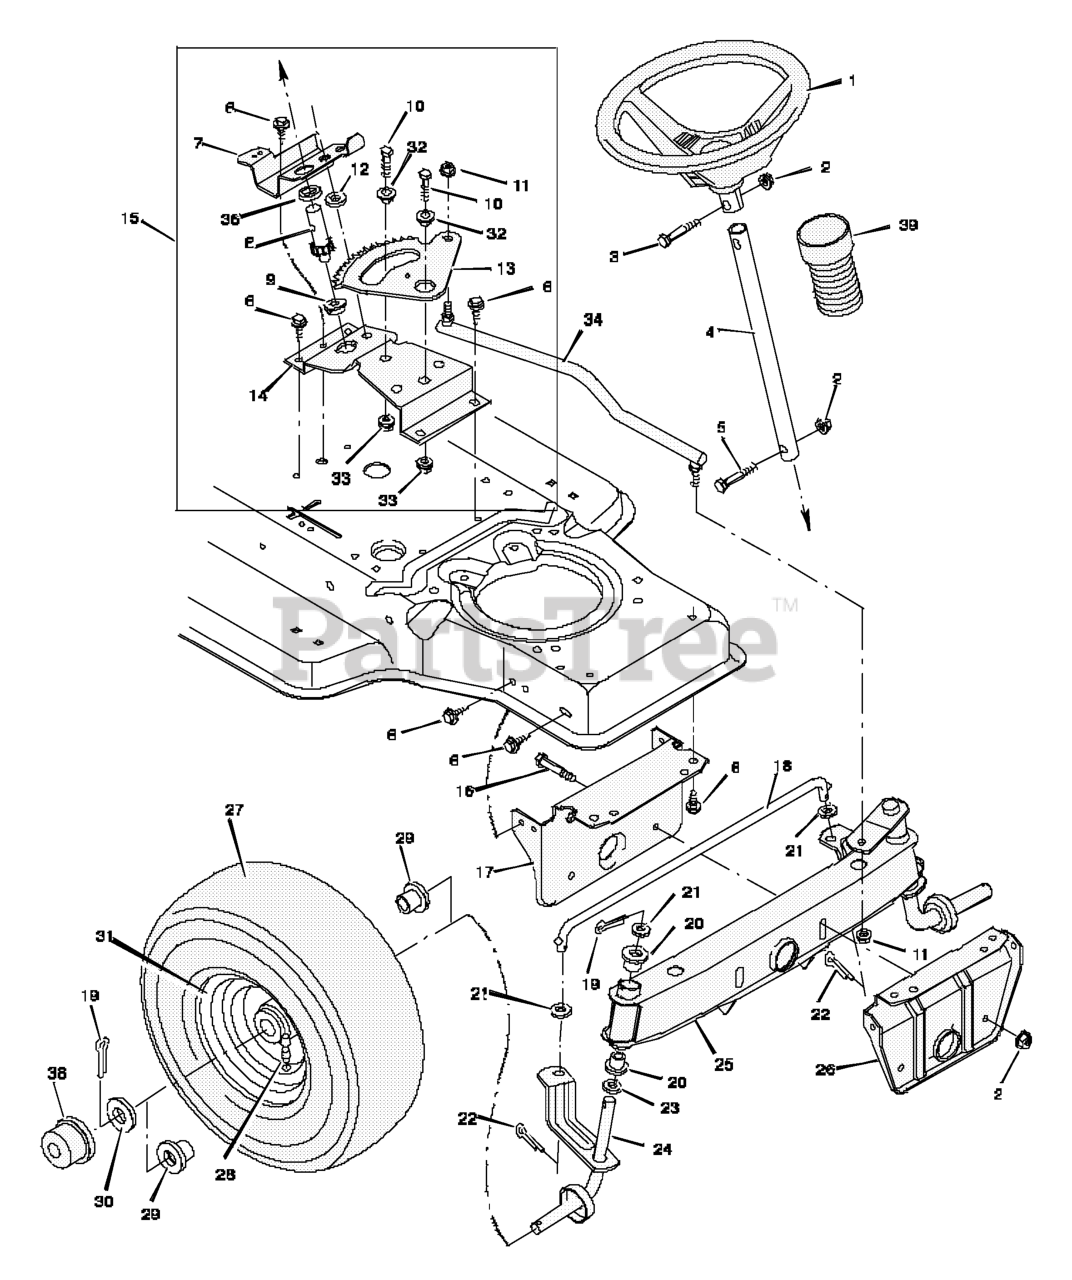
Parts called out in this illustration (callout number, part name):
1	Wheel, Steering
2	Nut, Hex
3	Bolt, Hex
4	Post, Steering
5	Bolt, Hex
7	Bracket, Sector
8	Gear, Pinion
9	Bearing
10	CAPSCREW, Hex Head, 5/16-18 x 1
11	Locknut, Flange
13	Gear, Sector
14	Bracket, Sector
15	Kit, Steering Gear
16	Bolt, Hex
17	Support, Rear Axle
18	Rod, Tie
19	Pin, Cotter
20	Bearing
22	Pin, Cotter
24	Spindle Assembly, Right
25	Spindle Assembly, Axle & Left
26	Support, Front Axle
28	Stem, Valve
29	Bearing, Wheel
31	Wheel & Tire Assembly
32	Bearing
33	Locknut, Flange
34	Link, Drag
36	Spacer, Pinion Gear
38	Hub Cap
39	Bellows
